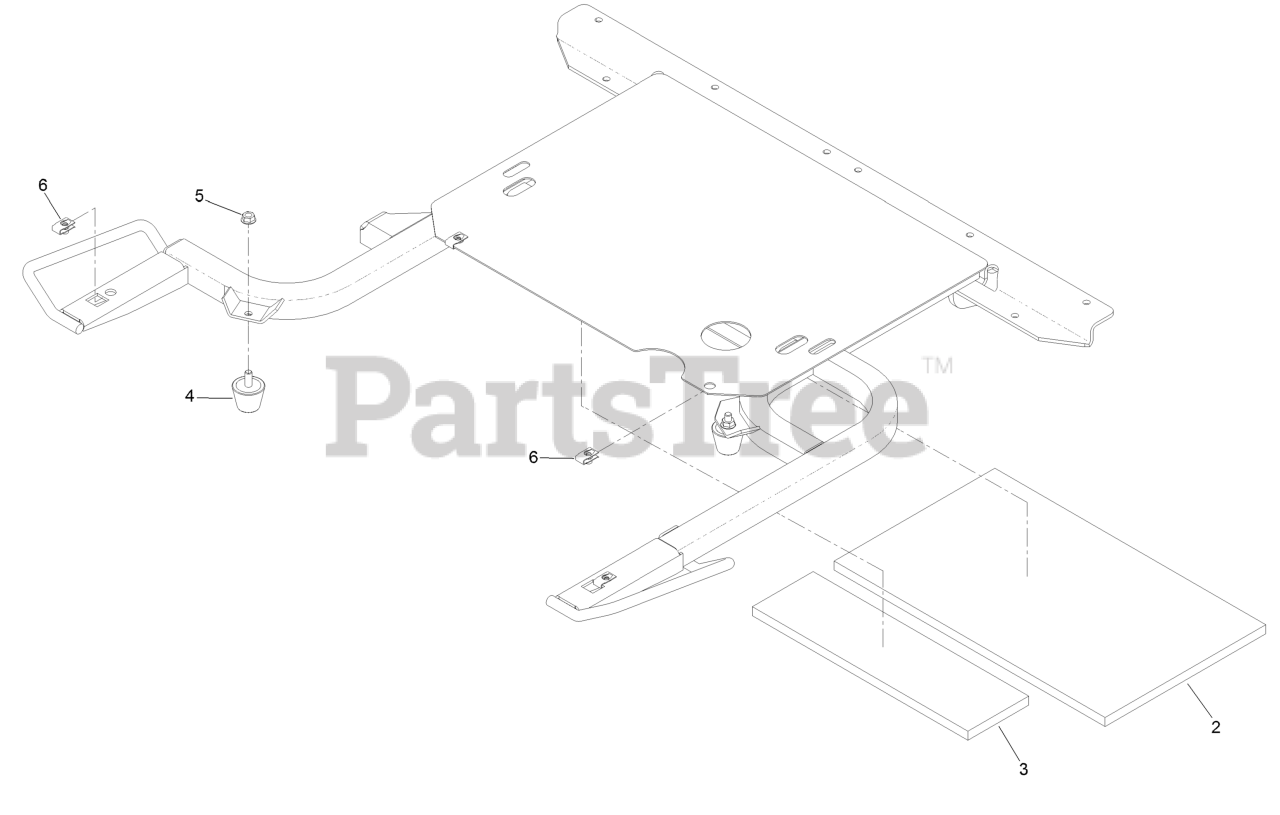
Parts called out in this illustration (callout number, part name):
2	Insulation-Foam Pad, Rear
3	Insulation-Foam Pad, Front
4	Bumper-Rubber
